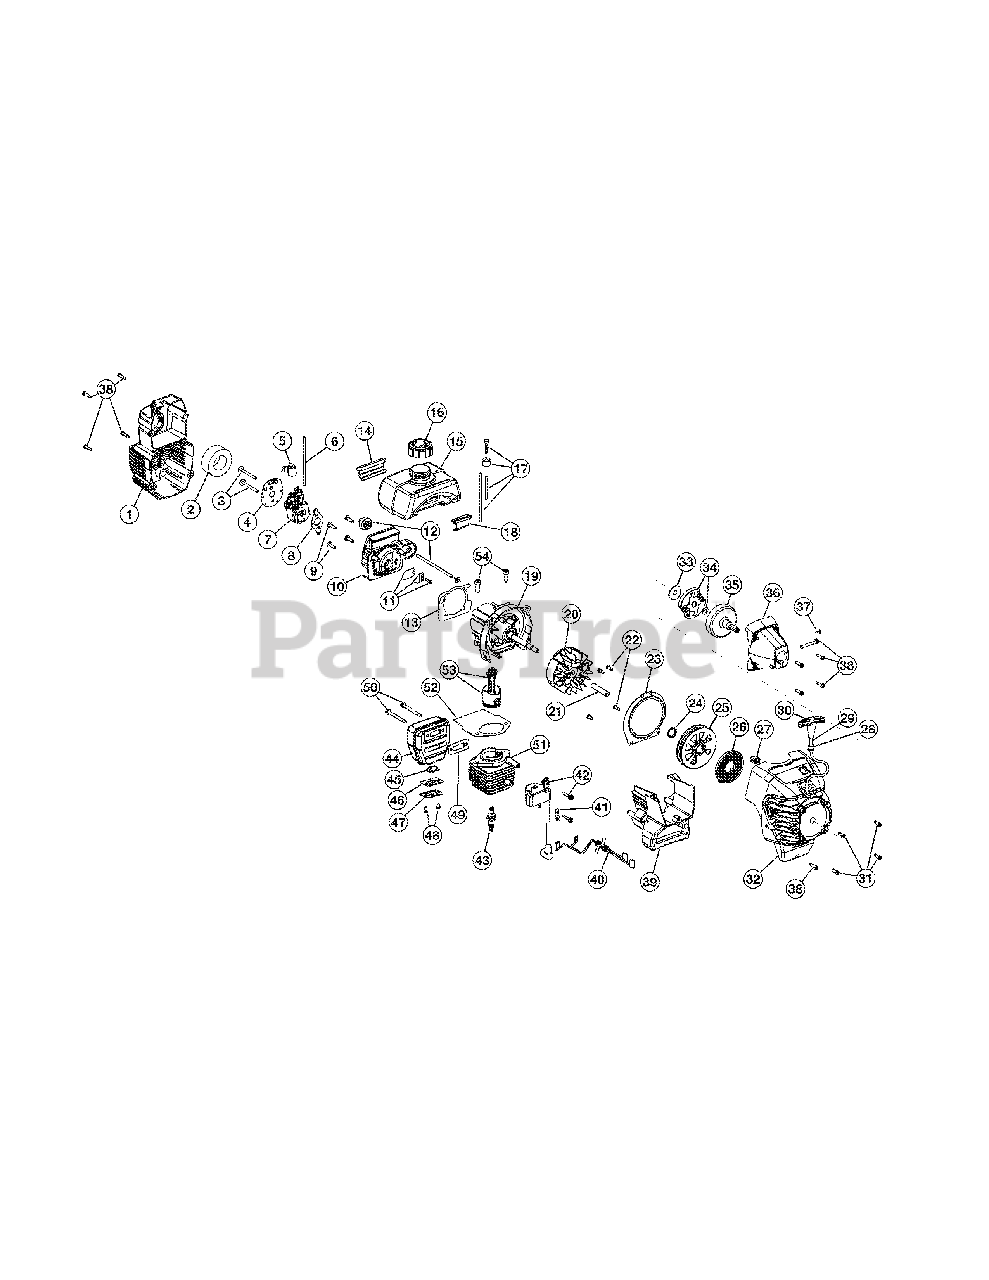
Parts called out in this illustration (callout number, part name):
1	Air Cleaner Cover Assembly (includes 2 & 38)
2	Air Cleaner Filter
3	Carburetor Mounting Screw Assembly
5	Choke Plate
5	Choke Lever
6	Fuel Return Line
7	Carburetor Assembly (includes 8 & 17)
8	Carburetor Gasket
9	Carb Mount Screw
10	Carb Mount Assembly (includes 9, 11, & 13)
11	Reed Assembly
12	Primer and Hose Assembly
13	Carburetor Mount Gasket
14	Rear Mounting Pad
15	Fuel Tank Assembly (includes 6, 16 & 17)
16	Fuel Cap Assembly
17	Fuel Line Assembly
18	Front Mounting Pad
19	Crank Case Service Assembly (includes 9)
20	Flywheel Assembly
22	Pressure Plate Screw
23	Pressure Plate
24	Pulley Retainer
25	Recoil Pulley Assembly
26	Recoil Spring
27	Rope Guide Retainer
28	Rope Guide
30	Pull Handle
31	Housing Screw
32	Starter Housing Assembly (includes 22-31 & 38)
33	Clutch Washer
34	Clutch Rotor Assembly
35	Clutch Drum Assembly
36	Clutch Cover Assembly (includes 37 & 38)
37	Anti-Rotation Screw
38	Cover Screw
39	Shroud Extension & Stand (includes 38)
40	Wire Leads and Sleeve
41	Ground Tab
42	Module Assembly
43	Spark Plug
44	Muffler Assembly (includes 45-50)
45	Spark Arrestor Screen
46	Spark Arrestor Plate
47	Spark Arrestor Hood
48	Spark Arrestor Screw
49	Exhaust Gasket
50	Muffler Mounting Bolt Assembly
51	Cylinder Assembly (includes 53 & 54)
52	Cylinder Gasket
53	Piston and Rod Assembly
54	Cylinder Bolt
